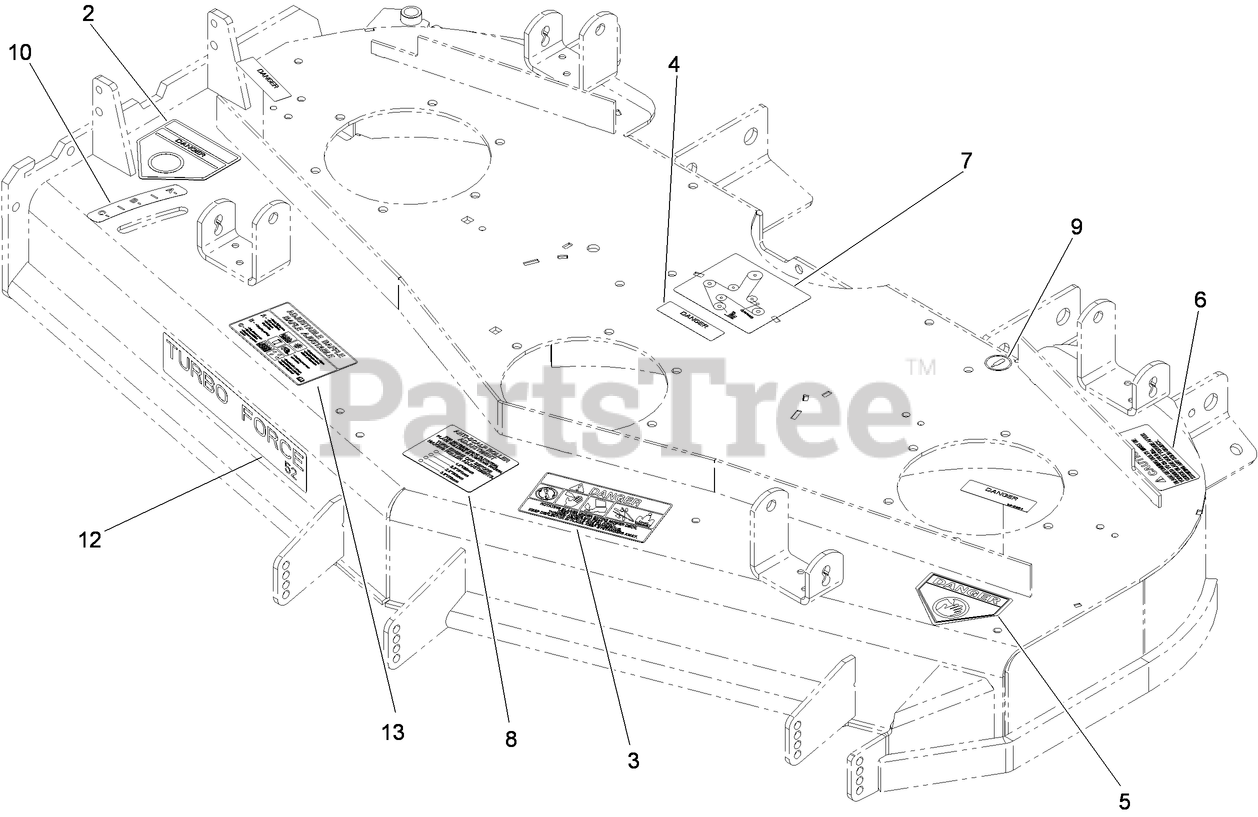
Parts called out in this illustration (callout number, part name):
2	DECAL-DANGER
3	DECAL-DANGER, THROWN OBJECT
4	DECAL-COVER, MISSING
5	DECAL-DANGER
6	DECAL-TORQUE
7	DECAL-ROUTING, BELT
8	DECAL-SCALP, ANTI
9	DECAL-GREASE
10	DECAL-SETTING, BAFFLE
13	DECAL-ADJUSTMENT, BAFFLE
